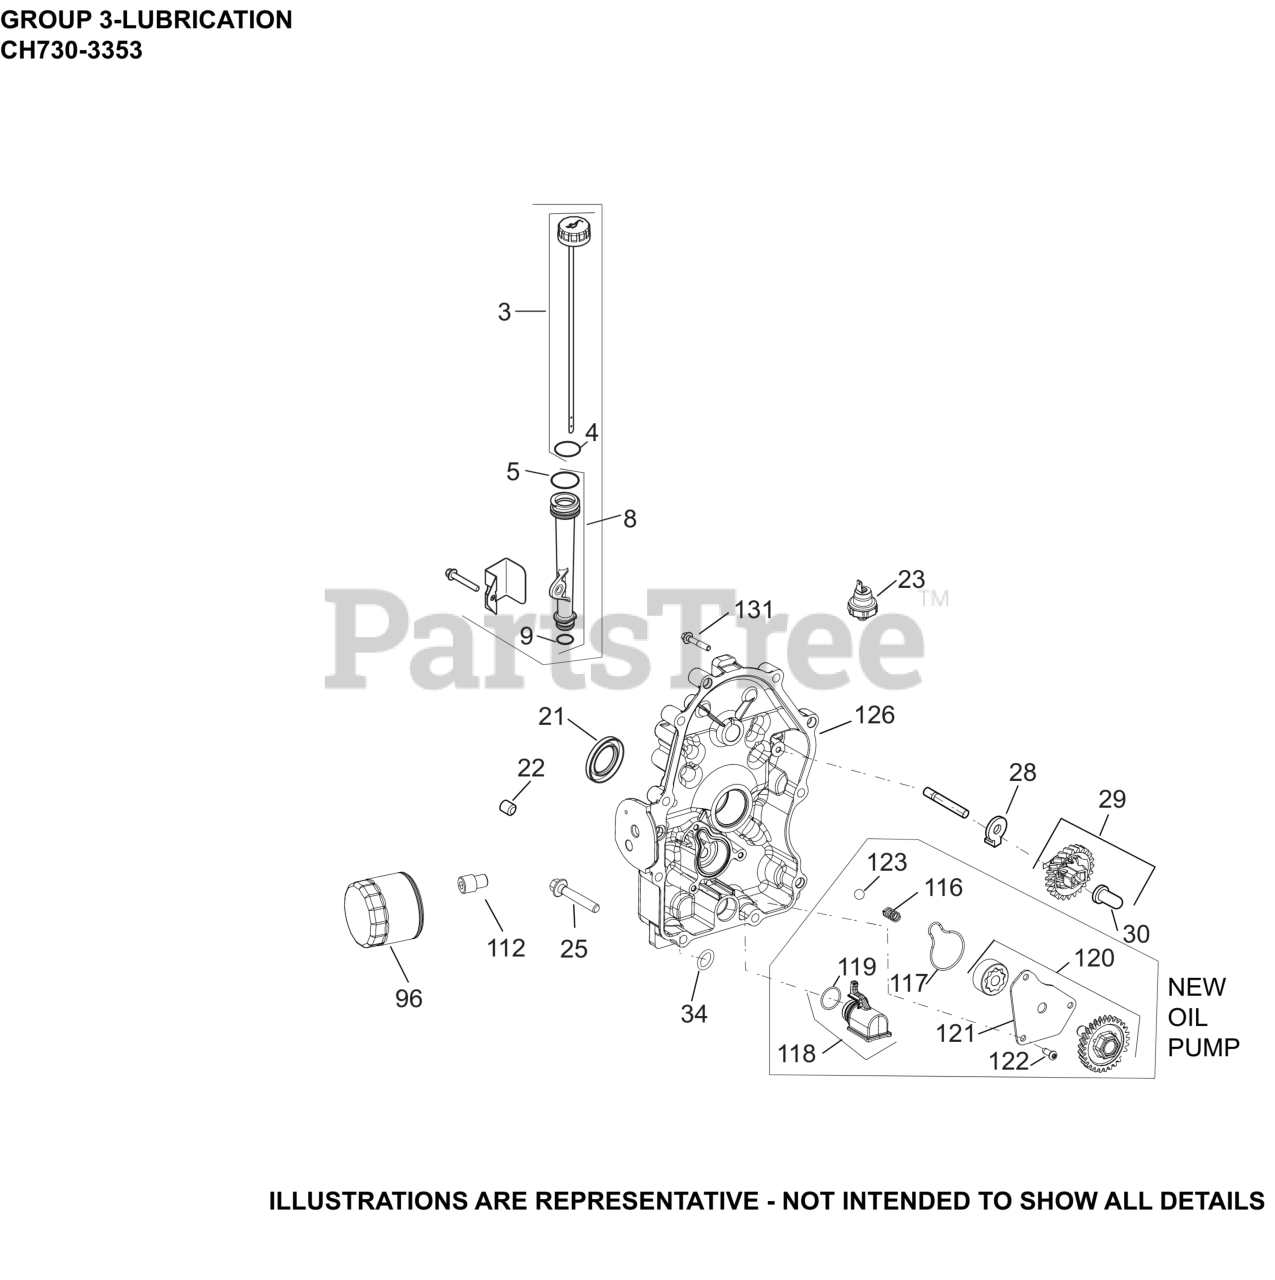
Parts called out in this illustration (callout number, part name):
3	KIT, DIPSTICK
4	O-RING, DIPSTICK
5	O-RING, UPPER OIL FILL TUBE
8	TUBE, OIL FILL ASSEMBLY
22	PLUG, CTSK PIPE 1/8"
23	SWITCH, OIL PRESSURE
25	SCREW, FLG M8X1.25X45
28	TAB, LOCKING
29	KIT, GOVERNOR GEAR W/PIN
30	PIN, GOVERNOR REGULATING
96	OIL FILTER
112	NIPPLE, OIL FILTER
116	SPRING, COMPRESSION
117	SEAL, OIL PUMP COVER
118	PICK-UP ASSEMBLY, OIL
119	O-RING, OIL PICK-UP
120	PUMP ASSEMBLY, OIL
121	COVER, OIL PUMP
122	SCREW, BUTTON HEAD
123	PRESSURE RELIEF BALL
126	CLOSURE PLATE ASSEMBLY (SERVICE)
131	SCREW, HEX FLANGE
NI	SHAFT, GOVERNOR GEAR
